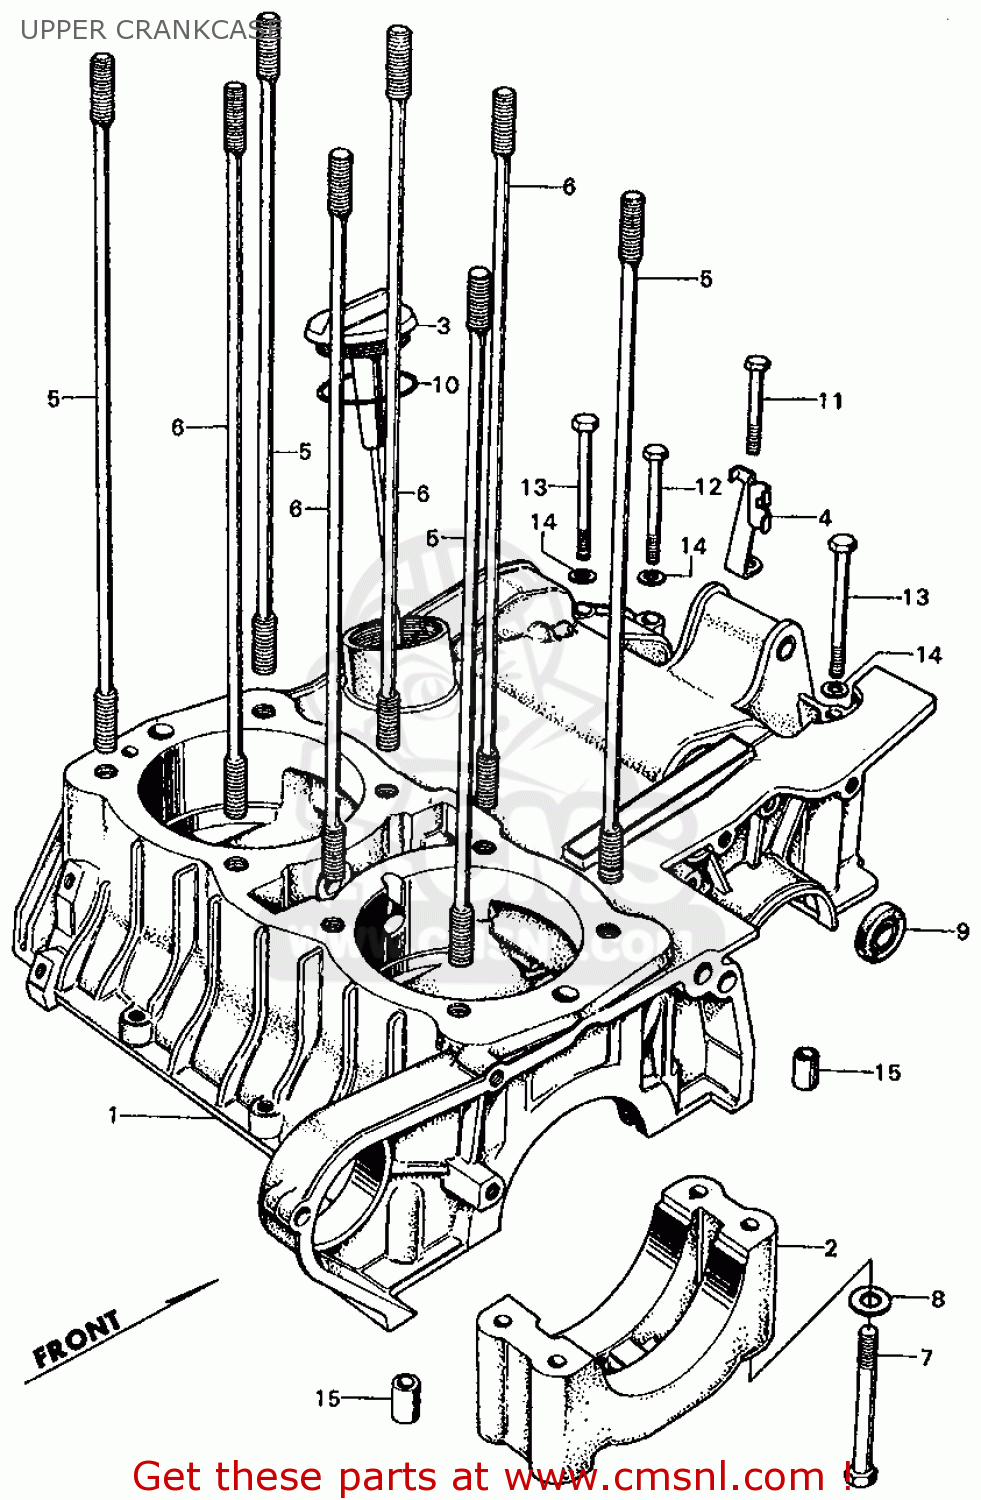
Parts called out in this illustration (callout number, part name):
1	CASE,UPPER CRANK
2	BEARINGCAP,CENTER
3	GAUGE,OIL LEVEL
4	CLAMPER, DYNAMO CORD
5	BOLT,CYLINDERSTUD
6	BOLT,CYLINDERSTUD
7	BOLT,HEX 8X71
8	WASHER,HEAD,8MM
9	OIL SEAL,12X25X45
10	O-RING,37X2.4
11	BOLT,HEX 6X40
12	BOLT,HEX 6X63
13	BOLT,HEX 6X80
14	WASHER PLAIN 6MM
15	DOWEL PIN
